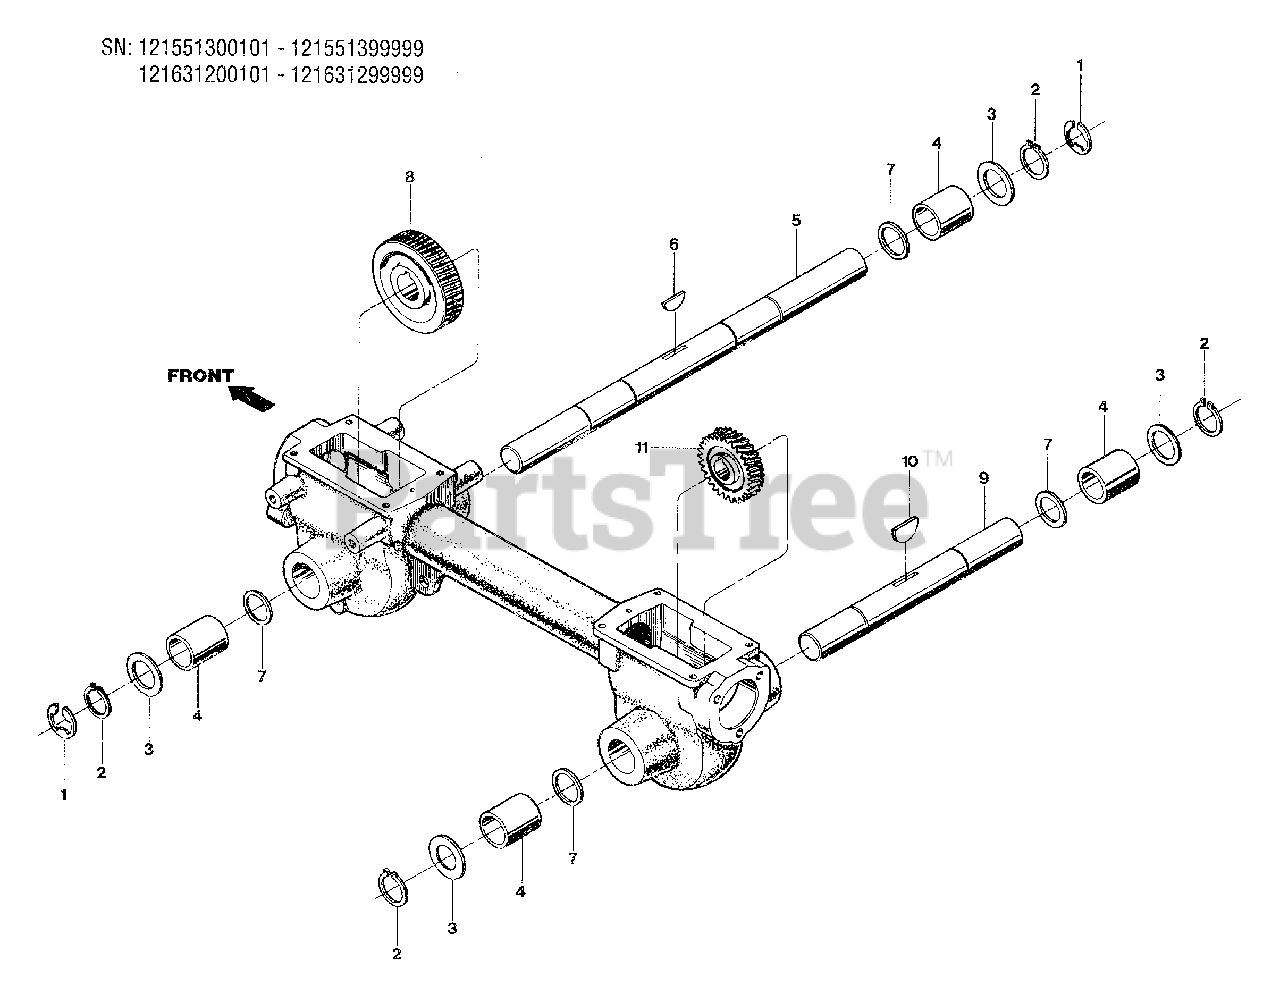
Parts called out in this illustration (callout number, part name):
1	Retainer-Snap Ring, "E" Type
2	Retainer-Snap Ring
3	Shim-0.062" Thick
4	Bushing-Bronze
5	Wheel Shaft
6	Key-Wheel Shaft, Hi Pro, 1/4 x 1
7	Spacer
8	Worm Gear-Wheel Shaft
9	Tiller Shaft
10	Woodruff Key-Tiller Shaft
11	Worm Gear-Tiller Shaft
